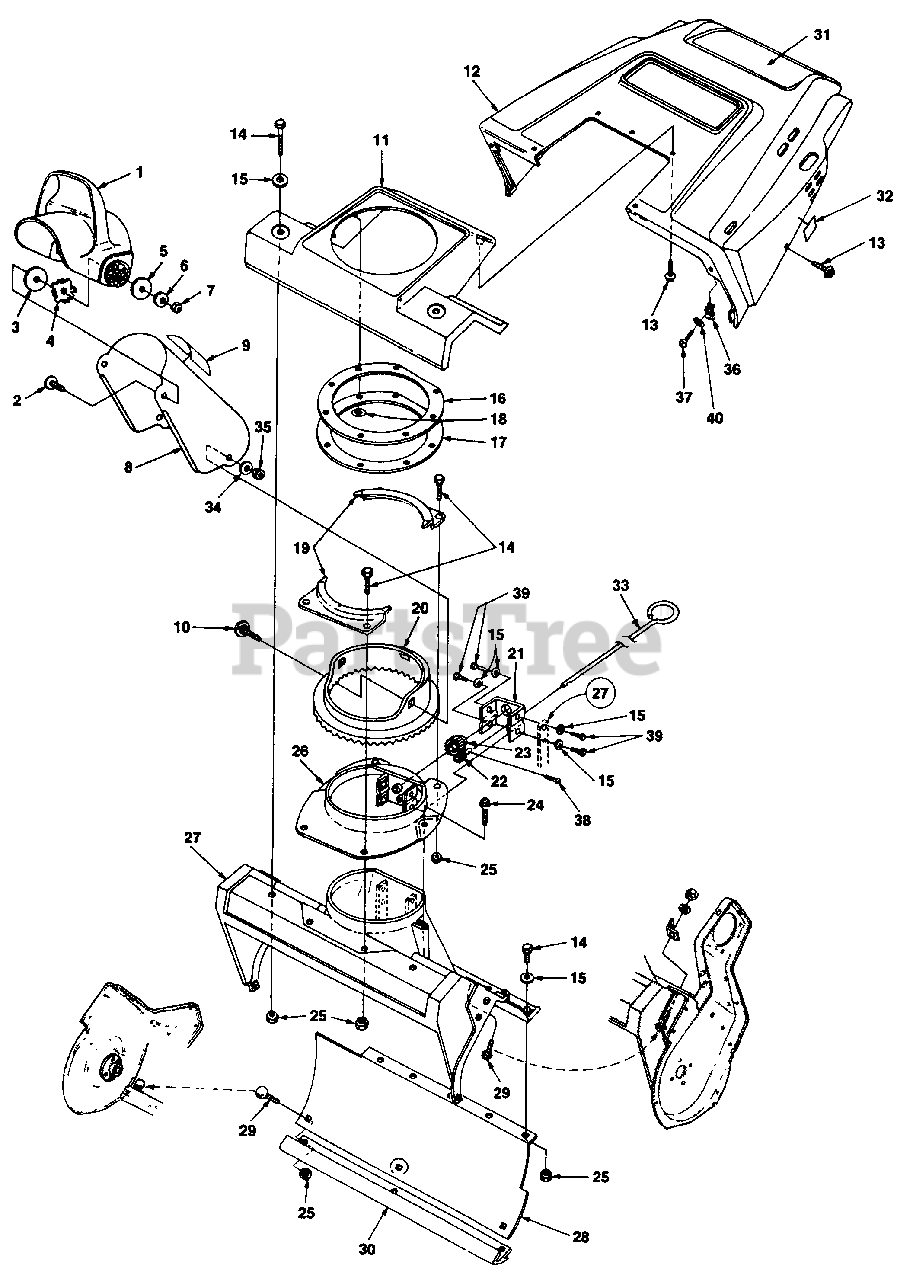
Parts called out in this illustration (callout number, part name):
1	DEFLECTOR
2	BOLT- Carr. 5/16-18 x 1"
3	WASHER- Flat rubber
4	WASHER- Octagon
5	WASHER- Flat 5/16"
6	WASHER- Belleville
7	NUT- Flange 5/16-18
8	CHUTE (w/decals)
9	DECAL- Warning
10	BOLT- Square neck 5/16-18 x 5/8"
11	COWLING- Transition
12	COWLING- Upper
13	SCREW- Thd. forming #10 x 5/8"
14	SCREW- Hex 1/4-20 x 3/4"
15	WASHER- Plain 1/4"
16	GASKET- Chute
17	RETAINER- Gasket
18	NUT- Push on
20	BASE- Chute
21	BRACKET- Gear
22	DRIVE- Gear
23	GEAR- Idler
24	SCREW- Plastite #12-14 x 1"
25	NUT- Flange 1/4-20
26	PLATE- Chute base
27	HOUSING- Auger
29	BOLT- Carr. Sq. Neck 1/4-20 x 3/4"
30	SCRAPER- Bar
31	DECAL- Console
32	DECAL- Warning
33	ROD- Crank adj.
34	WASHER- Lock 5/16"
35	NUT- Hex 5/16-18
36	U-CLIP- #10
37	SCREW- Hex Hd. #10-16 x 1 1/2"
38	PIN- Cotter 1/8 dia.
39	SCREW- Hex hd. 1/4-20 x 5/8"
40	WASHER- Flat #10
